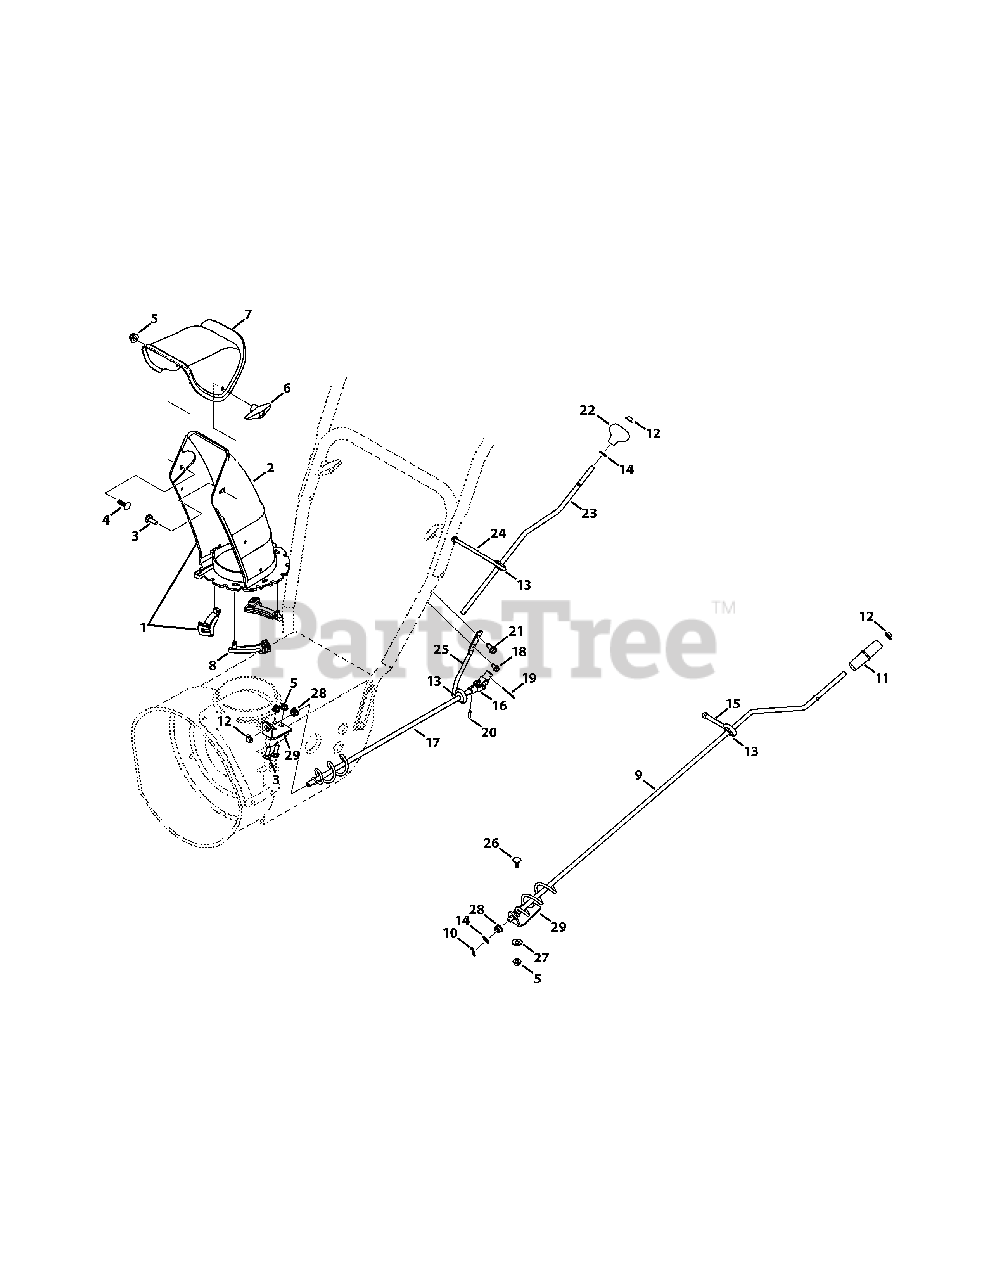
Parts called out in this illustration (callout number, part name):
1	Lower Chute Assembly
2	Lower Chute
3	Carriage Bolt, 5/16-18 x 1.00
4	Carriage Bolt, 5/16-18 x .750
5	Flange Lock Nut, 5/16-18
6	Wing Knob
7	Upper Chute
8	Flange Keeper
9	Chute Crank
10	Cotter Pin, .072 x 1.13
11	Crank Knob
12	Push Cap, 3/8
13	Rubber Grommet
14	Flat Washer, .375 x .738 x .063
15	Eye Bolt
16	Joint Assembly
17	Chute Crank
18	Taptite Screw, 1/4-20 x .500
19	Cotter Pin, .08 x 1.42
20	Pin, .156 x .875
21	Taptite Screw, 5/16-18 x 2.25
22	Shift Knob
24	Chute Rod Eye Bolt
25	Lower Chute Rod
26	Carriage Screw, 5/16-18 x 1.00
27	Flat Washer, .349 x .879 x .063
28	Plastic Bushing, .380 ID
29	Chute Crank Bracket
